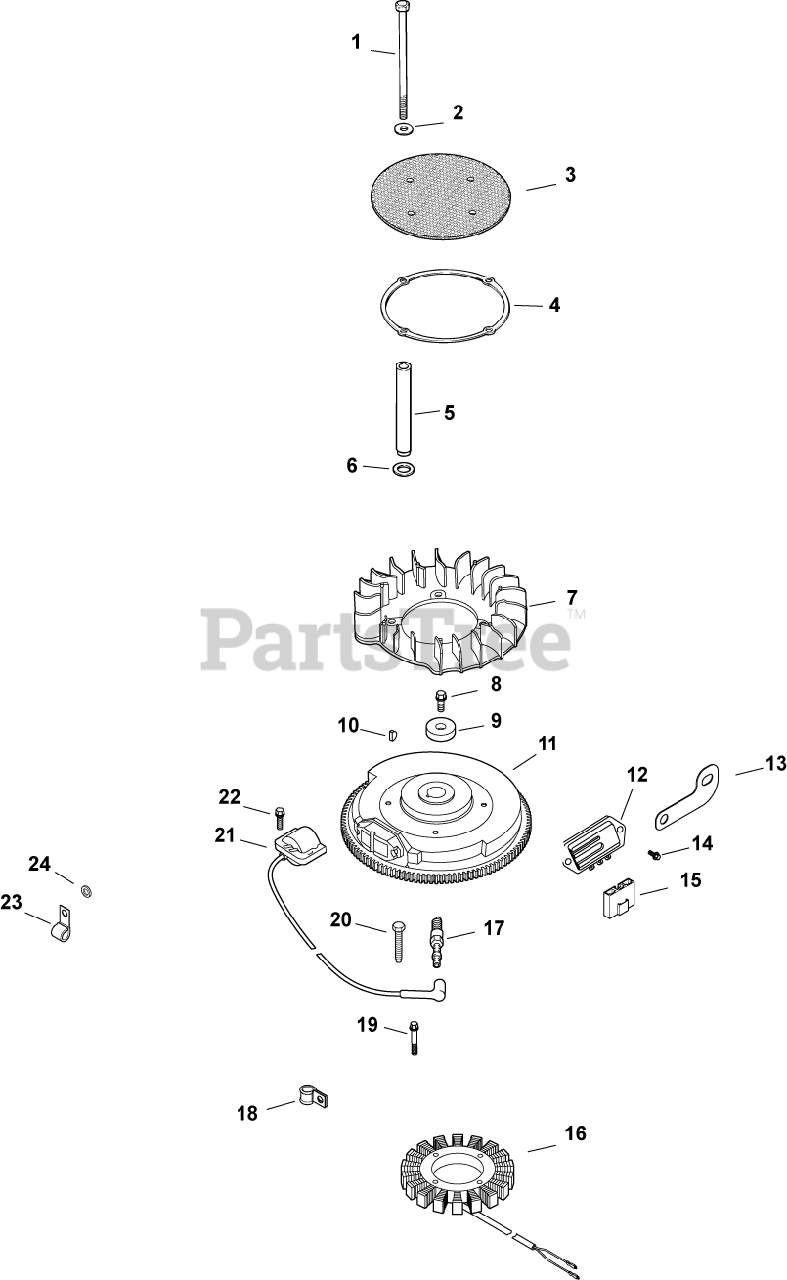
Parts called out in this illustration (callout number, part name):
1	SCREW, SOCKET TRUSS HD CAP
2	WASHER, FLAT 1/4" (O.D. 5/8")
3	SCREEN, GRASS
4	RING, SUPPORT USE 25 141 08-S
6	WASHER, SPRING 10 MM
8	SCREW, FLG M10X1.5X45 - (#25086361S)
9	WASHER, FLAT 13/32"
10	KEY, 3/16" X 5/8"
11	FLYWHEEL ASSEMBLY
12	REGULATOR/RECTIFIER
13	BRACKET, GROUND STRAP USE 24 518 12-S
14	SCREW, HEX FLANGE HI-LO
15	CONNECTOR
16	KIT, 15 / 20 AMP STATOR
17	PLUG, SPARK (PRO SERIES)
19	SCREW, SKT SET #10-24X1/4"
20	SCREW, M5X0.8X25 - (#25086402S)
21	KIT, MODULE IGNTN (CDI FIXED)
22	SCREW, FLG THD FRM M5X.8X20-(#25086399S)
23	CLIP, CABLE
24	WASHER, FLAT 1/4" (O.D. 1/2")
